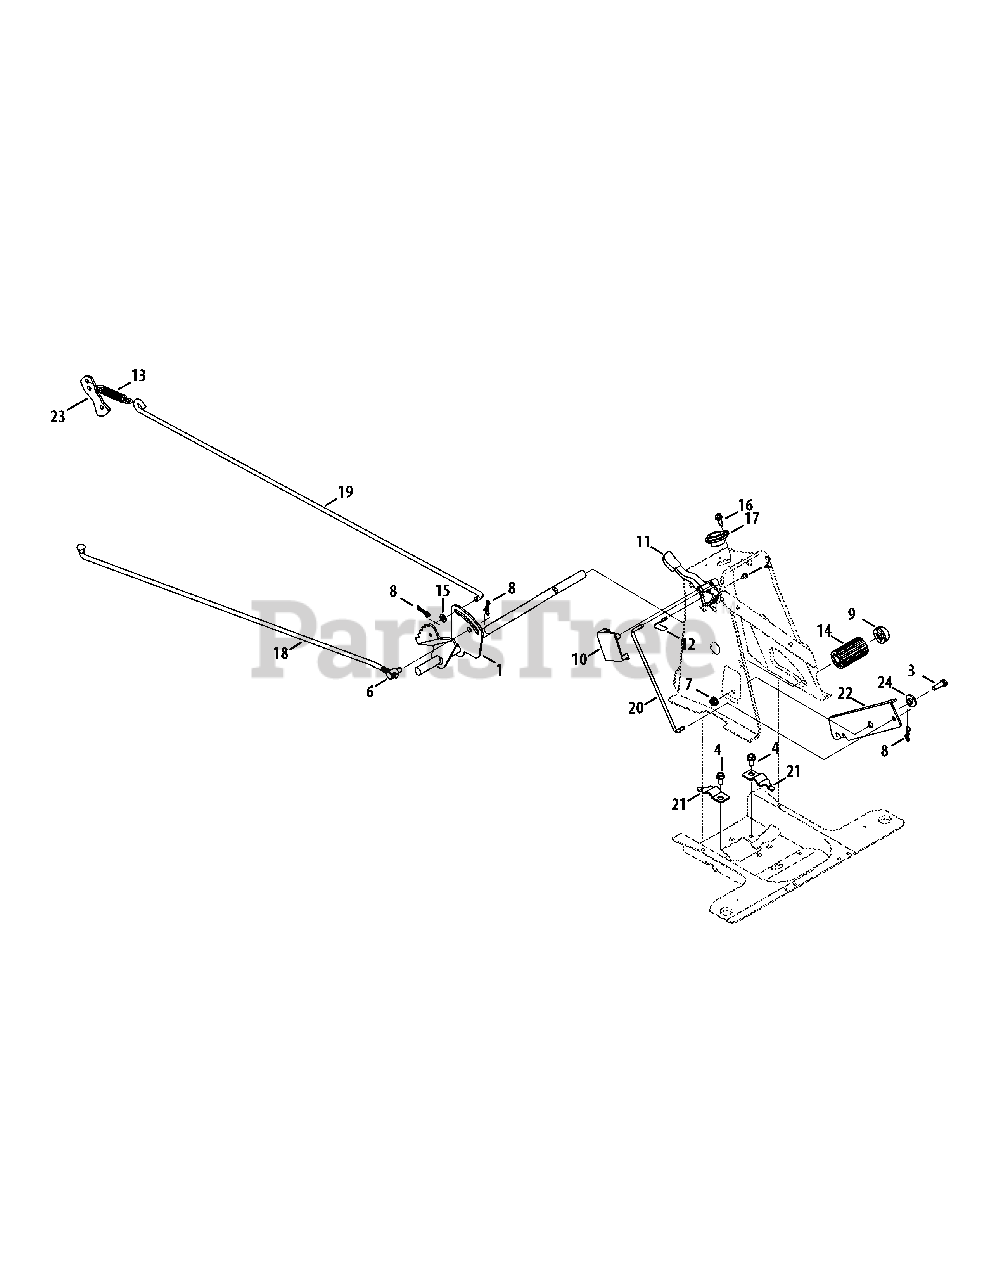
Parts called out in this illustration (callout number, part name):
1	Brake Pedal Assembly
2	Screw, #10-16:0.500
3	Hex Head Scerw, 5/16-18:1.00
4	Tap Screw, 5/16-18:.750
5	Hex Head Screw, 5/16-18:.75
6	Ferrule 3/8-24 X .375 Dia.
7	Flange Lock Nut, 5/16-18
8	Bow-Tie Cotter Pin, 72
9	Push Cap, 5/8
10	Speed Control Cover
11	Speed Lever, 6-SPEED
12	Shift Spring
13	Extension Spring, .59 OD X 4.00 LG
14	Foot Pad, 2.5" LG.
15	Flat Washer, .330x.630x.064
16	Shoulder Screw, .368 X.113, 1/4-20
17	Steering Col. Bearing, .880 ID X 1.36
18	Variable Speed Control Rod
19	Brake Rod
20	Speed Selector Control Rod
21	Pedal Strap Support Bracket, 5/8
22	Speed Latch Bracket
23	Brake Arm Lever
